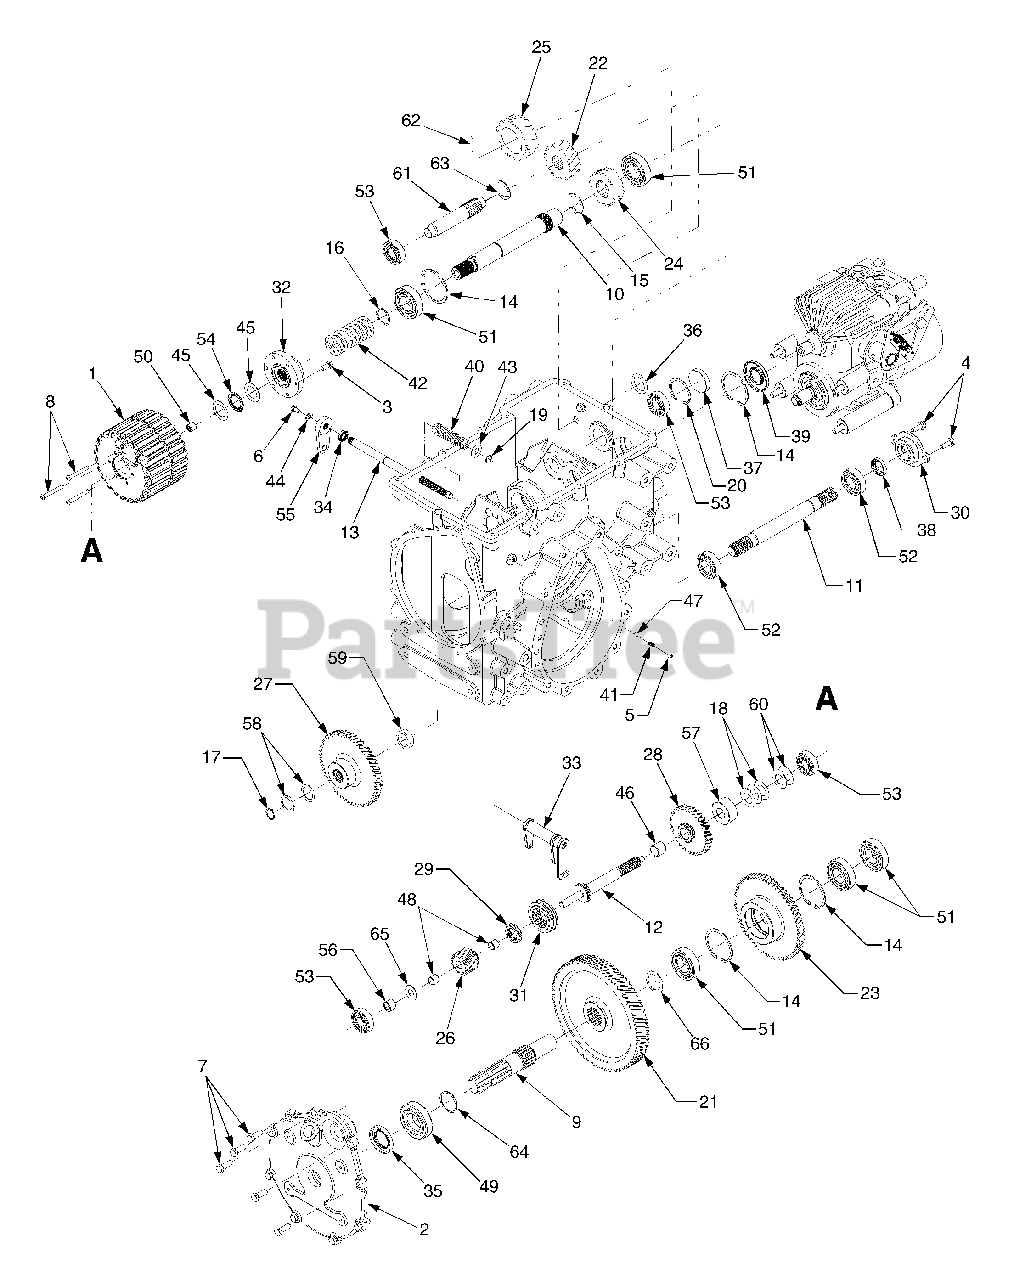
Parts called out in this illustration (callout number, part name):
1	Clutch Assembly, PTO
2	Housing, Rear
3	Screw, Hex Cap Lock, 1/4-20 x .62
4	Screw, Hex Wash Hd, 5/16-18 x .875 GR5
5	Screw, Cup Set, 5/16-18 x 3/8
6	Screw, Hex Cap, 1/4-20 x .5 GR5
7	Screw, Hex Cap Lock, 3/8-16 x 1.0 GR5
8	Screw, Round Hd, 6mm x 40mm
9	Shaft, 540 PTO
10	Shaft, PTO Input
11	Shaft, 2000 PTO
12	Shaft, PTO Back
13	Shaft, PTO Actuator
14	Ring, Retaining
15	Ring, Retaining
16	Ring, Retaining
17	Ring, Retaining
18	Washer, Flat, .793 x 1.368 x .01
19	Ring, Retaining
20	Ring, Retaining
21	Gear, 540 PTO: 81T
22	Gear, Wide, Auxiliary Drive Idler: 28T
23	Gear, 2000 PTO: 61T
24	Gear, Wide, Auxiliary Drive Pinion: 28T
25	Gear, Wide, Auxiliary Drive: 32T
26	Gear, 540 PTO Pinion: 14T
27	Gear, 2000 PTO Pinion: 54T
28	Gear, 2000 PTO Pinion: 34T
29	Gear, Spline Coupling
30	Cover, 2000 PTO
31	Collar, 2 Speed
32	Coupling, PTO
33	Actuator, PTO
34	Seal, Oil
35	Seal, Oil
37	Plug, Oil
38	Seal, Oil
39	Seal, Oil
40	Spring, Compression
41	Spring, Detent
42	Spring, Compression
43	Washer, Flat, .56 x 1.0 x .040
44	Washer, Flat, .25 x .630 x .0515
45	Washer, Thrust, 1.007 x 1.542 x .03
46	Bearing, Sleeve, 20mm x 23mm x 20mm
47	Ball, Detent
48	Bearing, Sleeve, 13mm x 15mm x 10mm
49	Bearing, Ball
50	Bearing, Needle
51	Bearing, Ball
52	Bearing, Ball
53	Bearing, Ball
54	Bearing, Needle Thrust
55	Arm, PTO Select
56	Spacer, 13mm x 20mm x 14mm
57	Spacer, .80 x 1.85 x .855
58	Washer, Flat, .865 x 1.145 x .03
59	Spacer, 1.0 x 1.25 x .39
60	Washer, Flat, .793 x 1.368 x .025
61	Shaft, Aux. Idler
62	Pin, Cotter, 1/16 x .5
63	Ring, Retaining 'E'
64	Ring, Retaining
65	Washer, Shim, .508 x 1.0 x .020
66	Washer, Shim, 1.25 x 1.8 x .020
66	Washer, Shim, 1.25 x 1.8 x .005
66	Washer, Shim, 1.25 x 1.8 x .010
